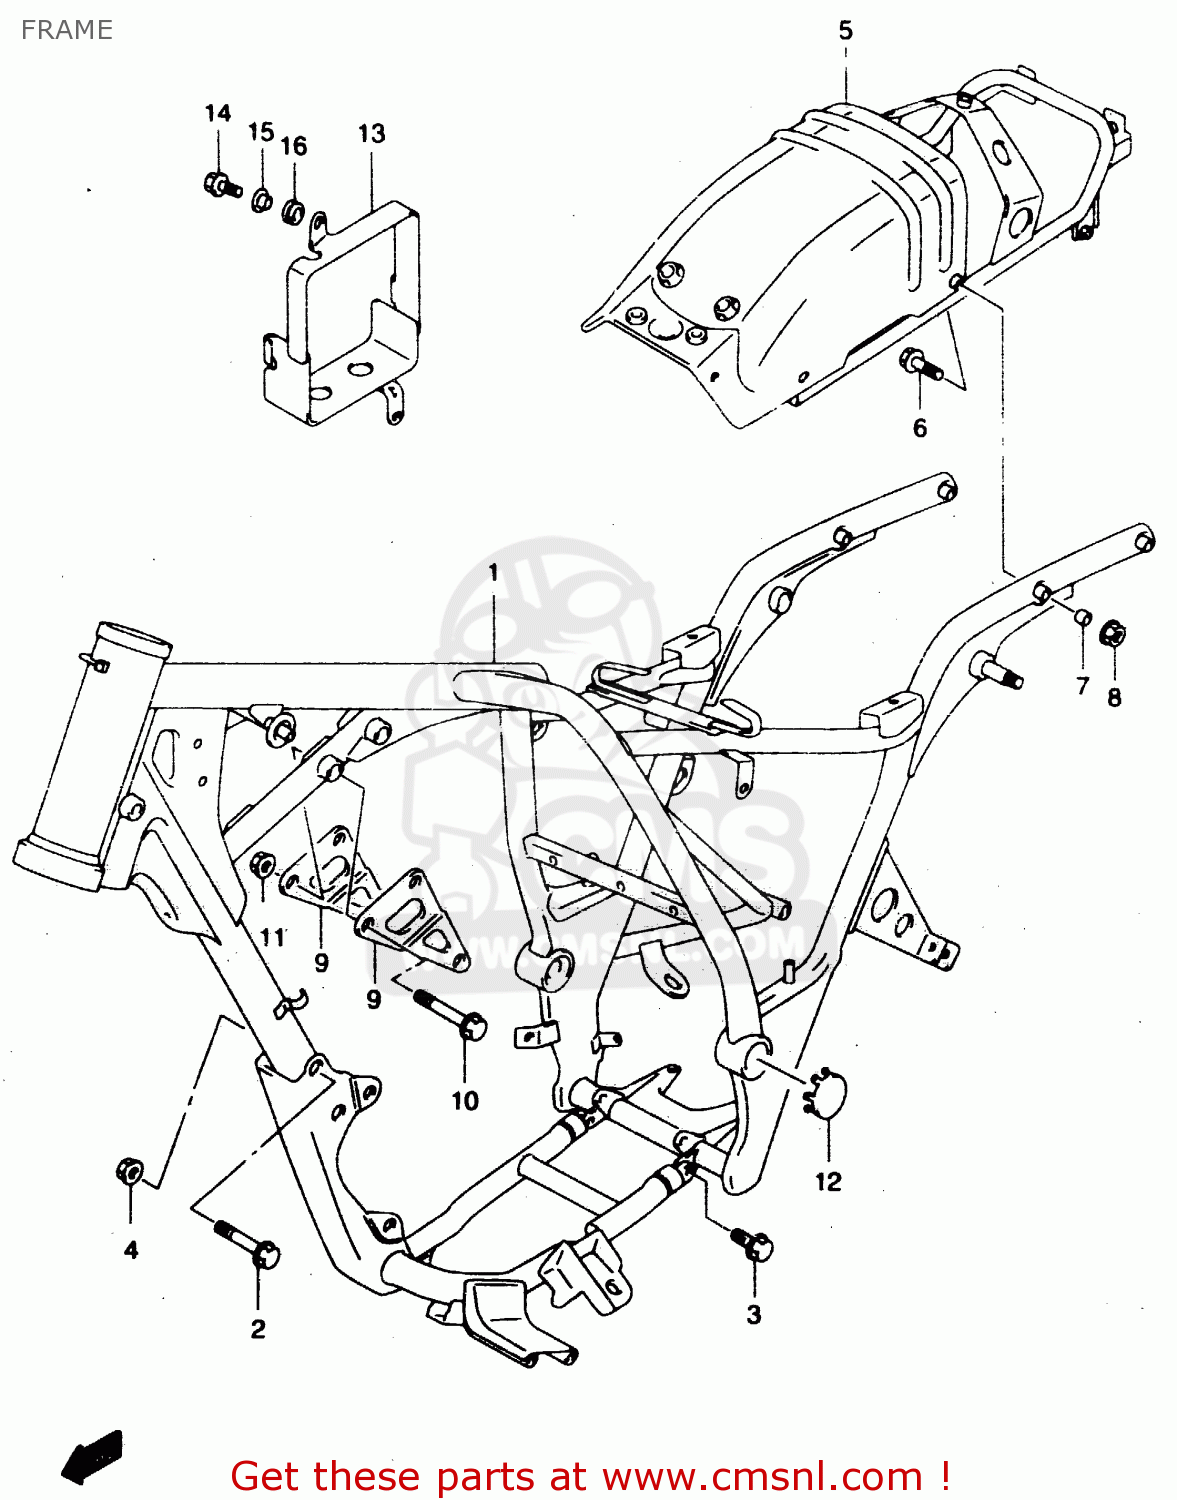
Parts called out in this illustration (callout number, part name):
1	FRAME (BLACK)
2	BOLT
3	BOLT
4	NUT
5	BRACE,RR FRAME
6	BOLT
7	SPACER(8.5X16X10)
8	NUT
9	PLATE,ENG MTG UPR
10	BOLT(8X50)
11	NUT
12	CAP,RR SWINGING ARM PIVOT,R
13	HOLDER,BATTERY
14	BOLT
15	WASHER
16	CUSHION
